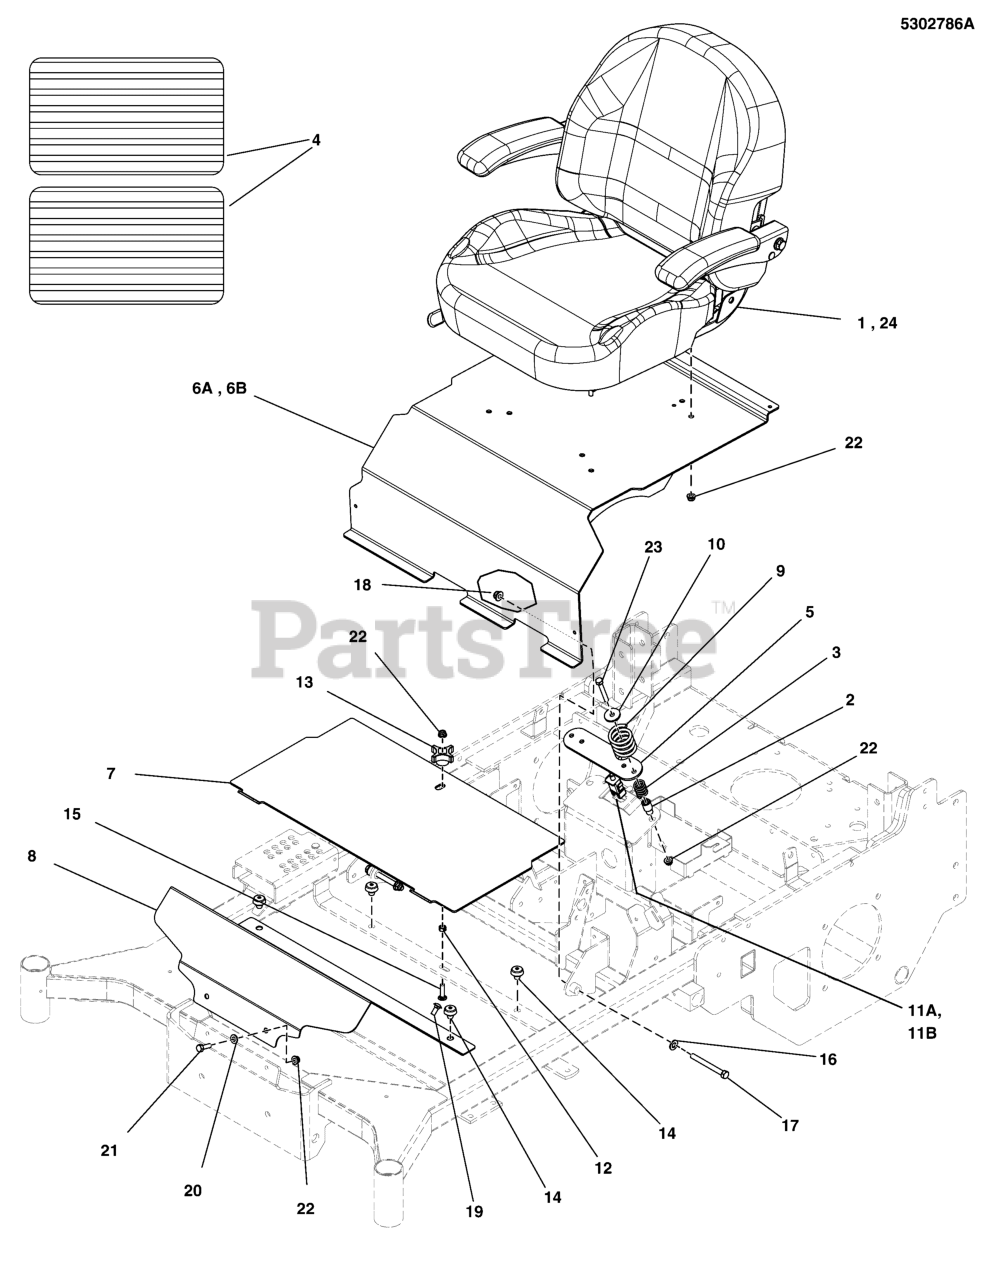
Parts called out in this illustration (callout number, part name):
1	SEAT, 2012
2	SPACER, .33 X .66 X 1.31 SHLDR, CZ
3	SPRING, COMP 720ID X 1.310LG X .118WIRE
4	SAFETY WALK, 10.00 X 19.00
5	PLATE, SEAT SWITCH - RED
6A	ASSM, SEAT PLATE W/ DECALS, F200XT - RED (5408309B)
6B	ASSM, SEAT PLATE W/DECALS,200XT-FRS (5413370B)
7	PLATE, REMOVABLE FLOOR, 200XT - RED
8	PLATE, RIGID FLOOR, 200XT - RED
9	SPRING, SEAT SUPPORT
10	WASHER, .34 X 1.25 X 10 GA
11A	SWITCH, PLUNGER, NO/NO SNAP-IN
11B	SWITCH, PLUNGER, NO SINGLE POLE SNAP-IN
12	NUT, 5/16-18, HEX, CNTR LK,ZINC PHOS/OIL
13	KNOB-INT THR .312-18 4-ARM 2.12WD 1.06LG
14	MNT, VBRTN, RBBR
15	BOLT, 5/16-18 X 1-1/4, CARRIAGE CZ
16	WASHER, 3/8 SAE
17	BOLT, 3/8-16 X 3-1/2" GD5 CZ
18	NUT, 3/8-16 HEX NYLOCK FLANGE
19	BOLT, 5/16-18 X 3/4, CARRIAGE
20	WASHER, 5/16" SAE
21	BOLT, 5/16-18 X 1 GD5 CZ
22	NUT, 5/16-18 HEX NYLOCK FLANGE
23	BOLT, 5/16-18 X 2-1/4 GD5 YZ
24	SEAT, CI3, SEAT'S INC. 2016
